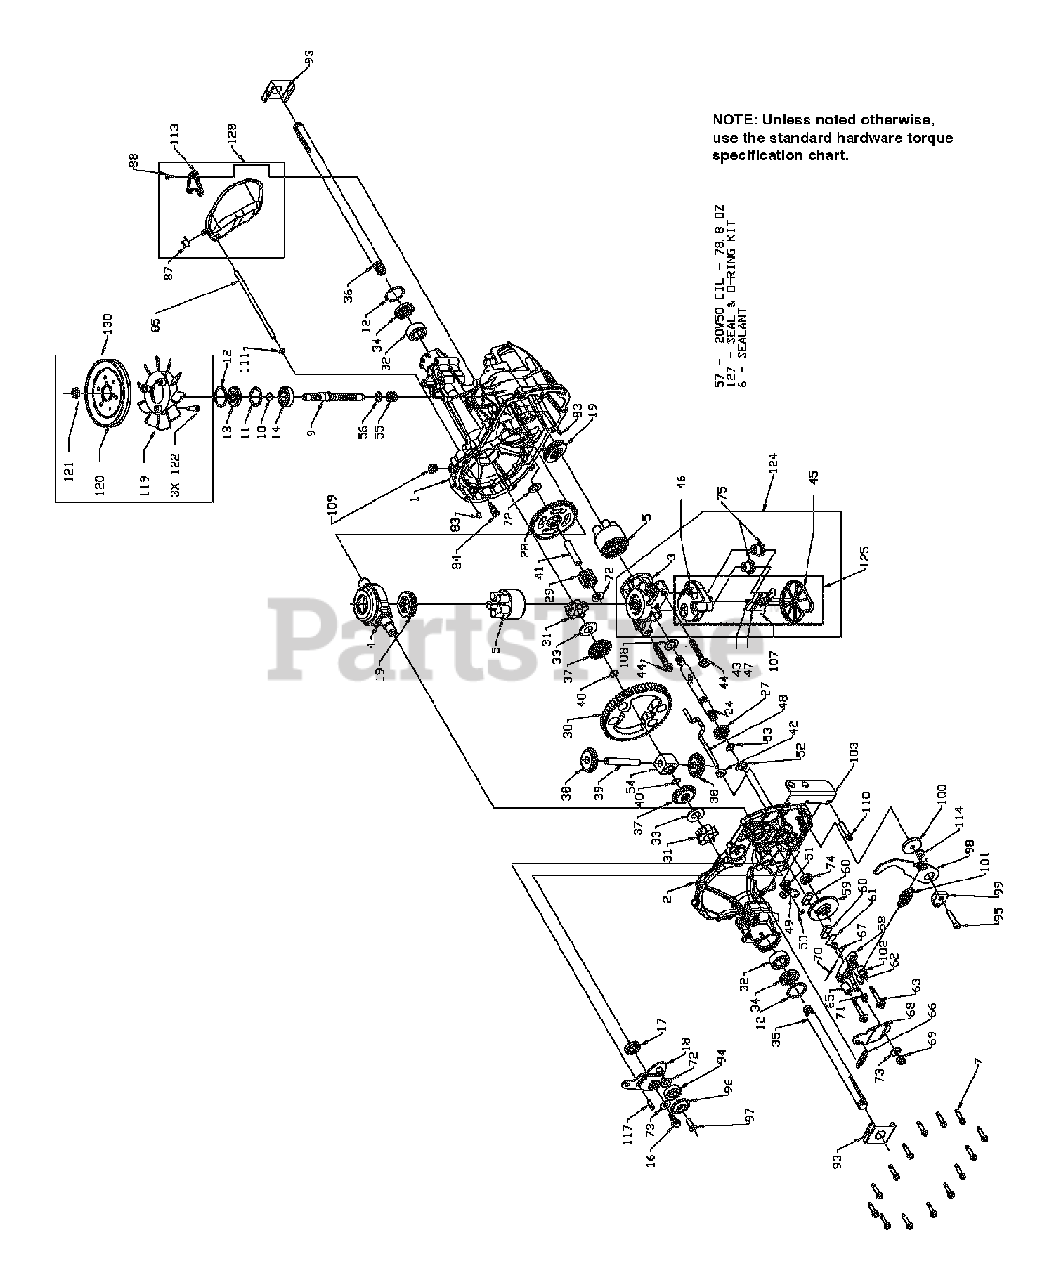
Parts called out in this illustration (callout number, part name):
6	SEALANT
9	SHAFT, INPUT
10	RING - RETAINING
12	RING - RETAINING
14	BALL BEARING
32	OUTBOARD SLEEVE BEARING
35	AXLE SHAFT - RH
36	AXLE SHAFT - LH
55	SPRING - HELICAL COMPRESSION
56	WASHER
57	20W-50 OIL
101	HYDRO RETURN SPRING
119	FAN, 6, 10 BLADE
128	EXPANSION TANK KIT
130	FAN/PULLEY KIT (includes Ref. 119)
